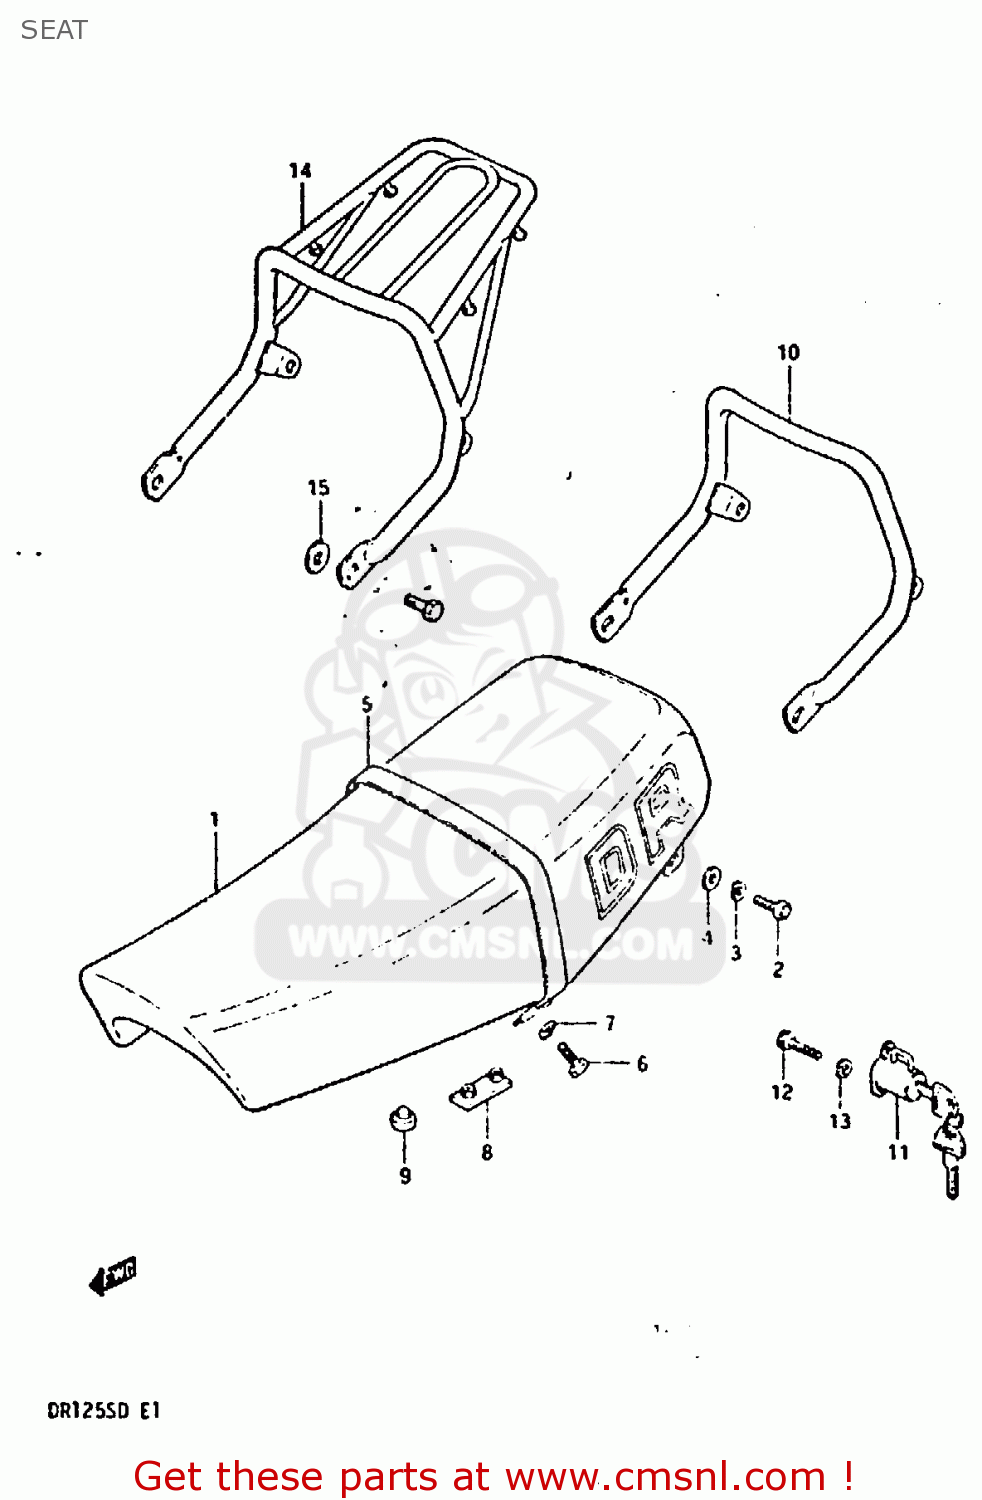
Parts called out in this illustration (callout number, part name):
1	SEAT ASSEMBLY
2	BOLT
3	LOCK WASHER
4	WASHER
5	BAND,SEAT
6	BOLT
7	LOCK WASHER
8	CUSHION
9	CUSHION
11	LOCK ASSEMBLY,HELMET
12	BOLT 6X11
13	LOCK WASHER
14	CARRIER
16	BOLT
